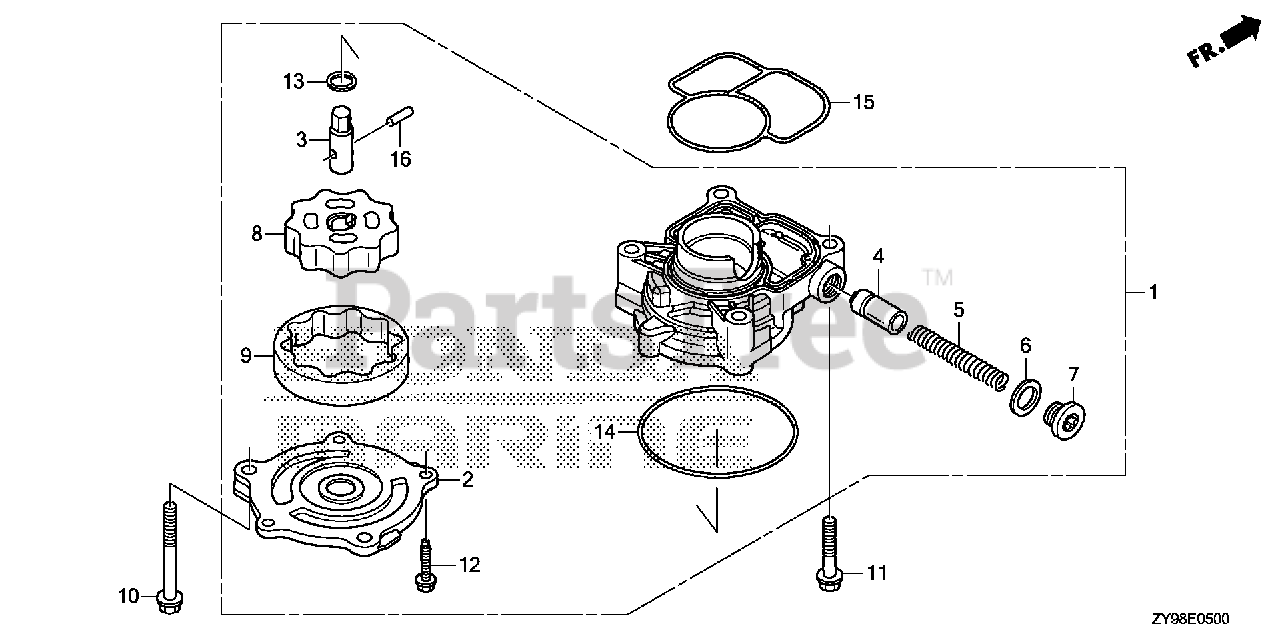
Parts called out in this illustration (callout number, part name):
1	PUMP ASSY., OIL
2	COVER, OIL PUMP
3	SHAFT, OIL PUMP
4	VALVE, RELIEF
5	SPRING, RELIEF VALVE
6	WASHER, SEALING (18MM)
7	BOLT, SEALING (18MM)
8	ROTOR (INNER)
9	ROTOR (OUTER)
10	BOLT, FLANGE (8X60)
11	BOLT, FLANGE (8X40)
12	BOLT, FLANGE (6X18) (CT200)
13	WASHER, THRUST (13MM)
14	O-RING, PUMP COVER
15	O-RING, OIL PUMP
16	ROLLER (5X17.8)
